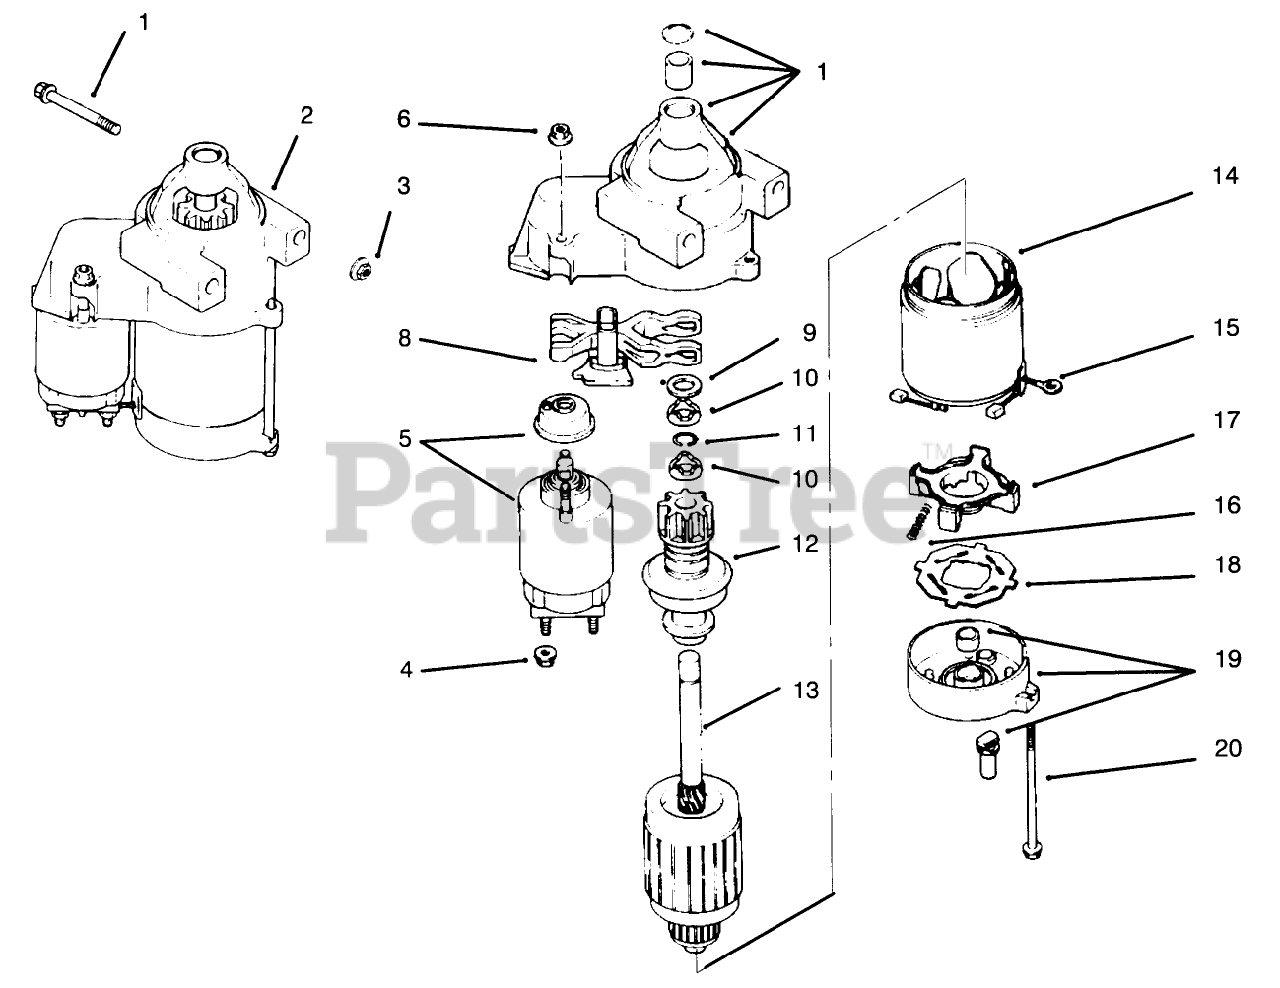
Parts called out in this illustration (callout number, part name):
1	Scew
2	Starter Solenoid Shift (Incl. Ref. #4-20)
3	Nut
4	Nut
5	Cap Drive End
6	Nut
7	Solenoid
8	Lever Starter Drive
9	Washer
10	Nut
11	Ring-Retaining
12	Drive Pinion
13	Armature
14	Frame
15	Kit-Brush (Incl. Ref. #16)
16	Spring Brush
17	Holder-Brush
18	Insulator
19	Cap-Commutator End
20	Bolt
